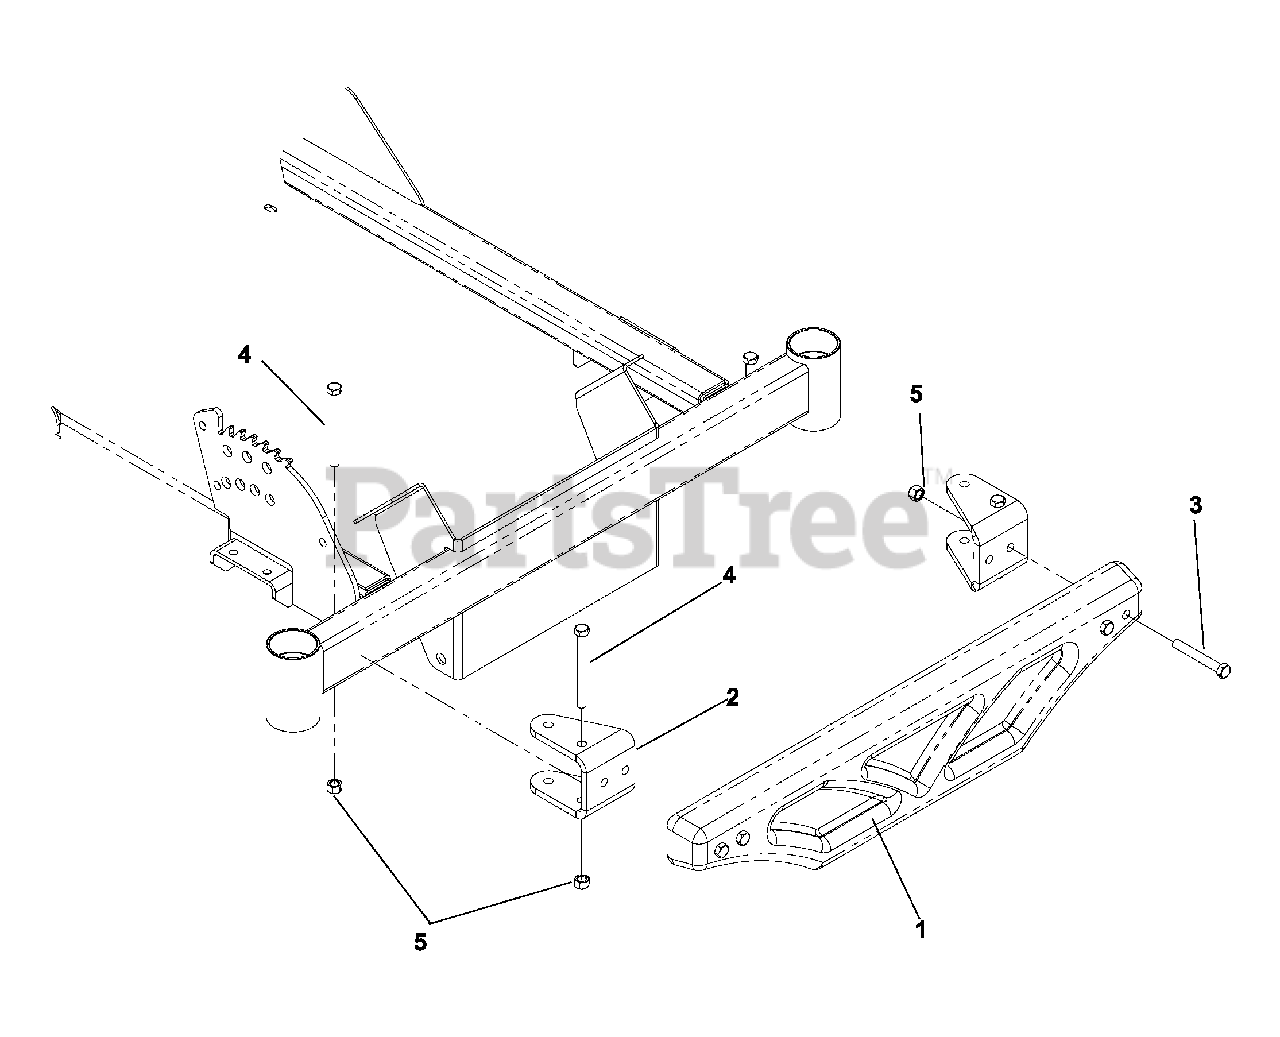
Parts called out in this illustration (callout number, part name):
1	CAST WEIGHT
2	BRACKET, WEIGHT
3	HEX SCREW 3/8-20 X 2.75
4	HCS3/8-16.X
5	NUT 3/8-16 NYLOC
